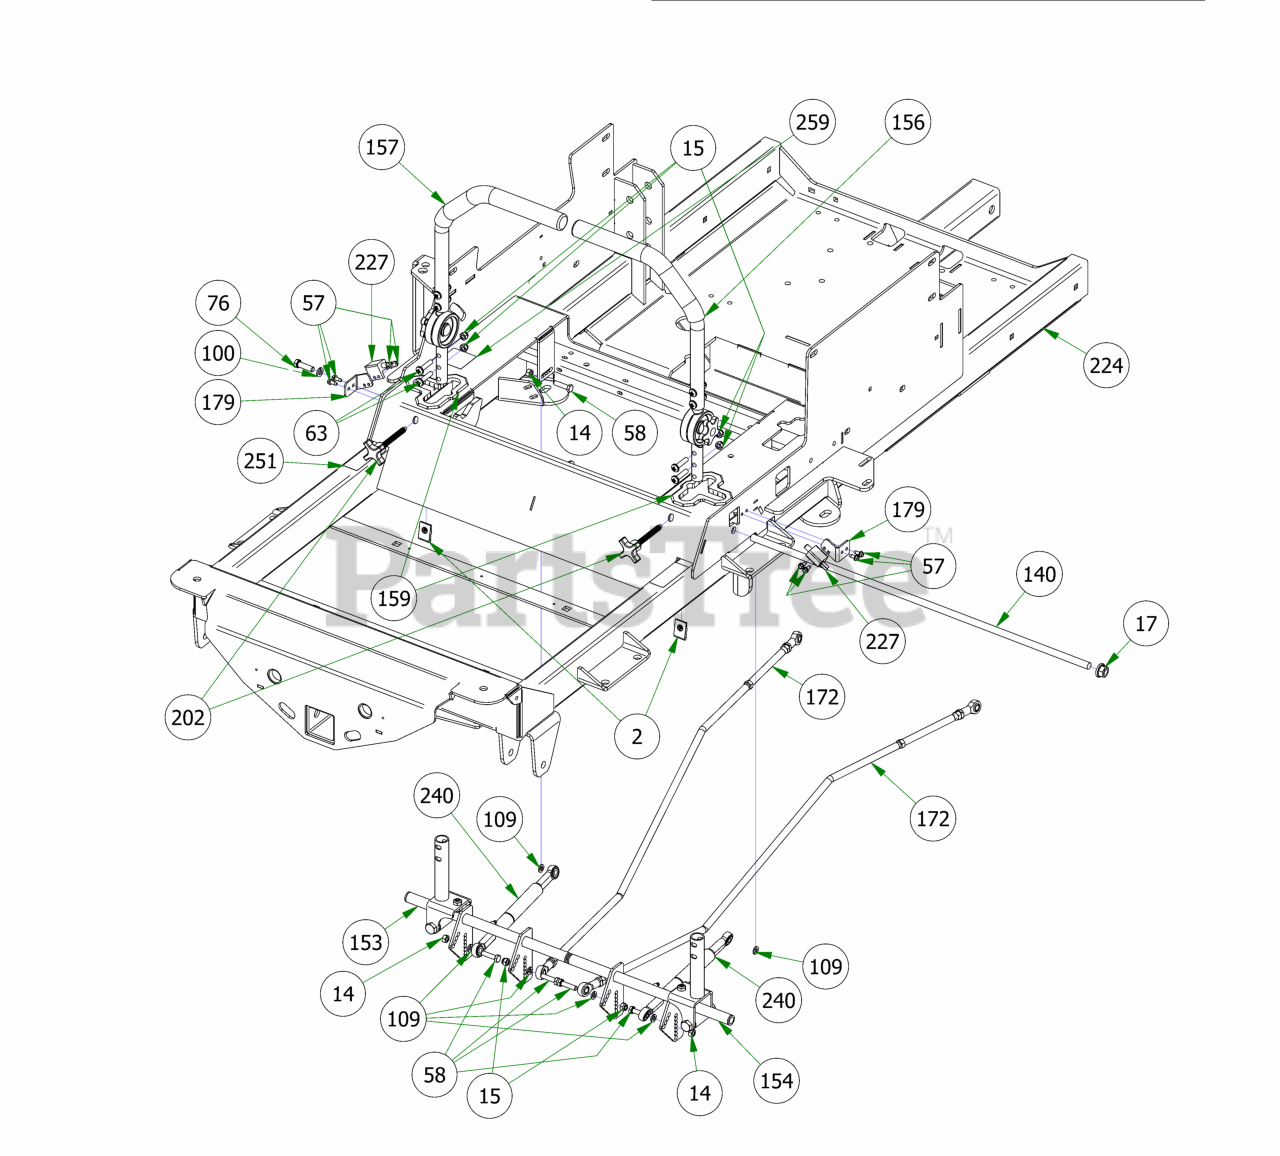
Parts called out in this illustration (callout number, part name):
2	Extruded Nut 3/8"-16 3/4" Hole Center With Patch
14	5/16-18 HEX NUT ZINC
15	5/16-18 NYL INS L/N ZC
17	1/2-13 NYLON INSERT FLANGE LOCKNUT ZINC
57	12-24 X 1/2 HEX WASHER UNLSOT F TCS ZINC
58	5/16-18 X 1-1/4 HEX C/S (GR.5) ZC
63	5/16-18 x 1 3/8" Futton Head Torx Drive Bolt
76	3/8-16 X 1-1/4 HEX CAP SCREW (GR.5) ZINC
100	3/8 SPLIT LOCKWASHER ZINC
109	5/16 SPLIT LOCKWASHER ZINC
140	2019 Steering Actuator Rod
153	2019 R Series RH Arm Rod Assembly
154	2019 R Series LH Arm Rod Assembly
156	2019 Left Hand ADJ. Steering Arm Kit
157	2019 Right Hand ADJ. Steering Arm Kit
159	Snap-in Drive Arm Bushing
172	2019 Renegade Push Rod Assembly
179	2019 Arm Switch Bracket
202	Speed Limiting Knob 3/8-16X 3"
224	2019 Renegade Gas Frame - Powdercoated
227	Safety Switch
240	2019 SROID Damper With Spherical Rod Ends
251	2018 LH/RH Steering Control Decal Roll
259	2019 Deck Release Decal
